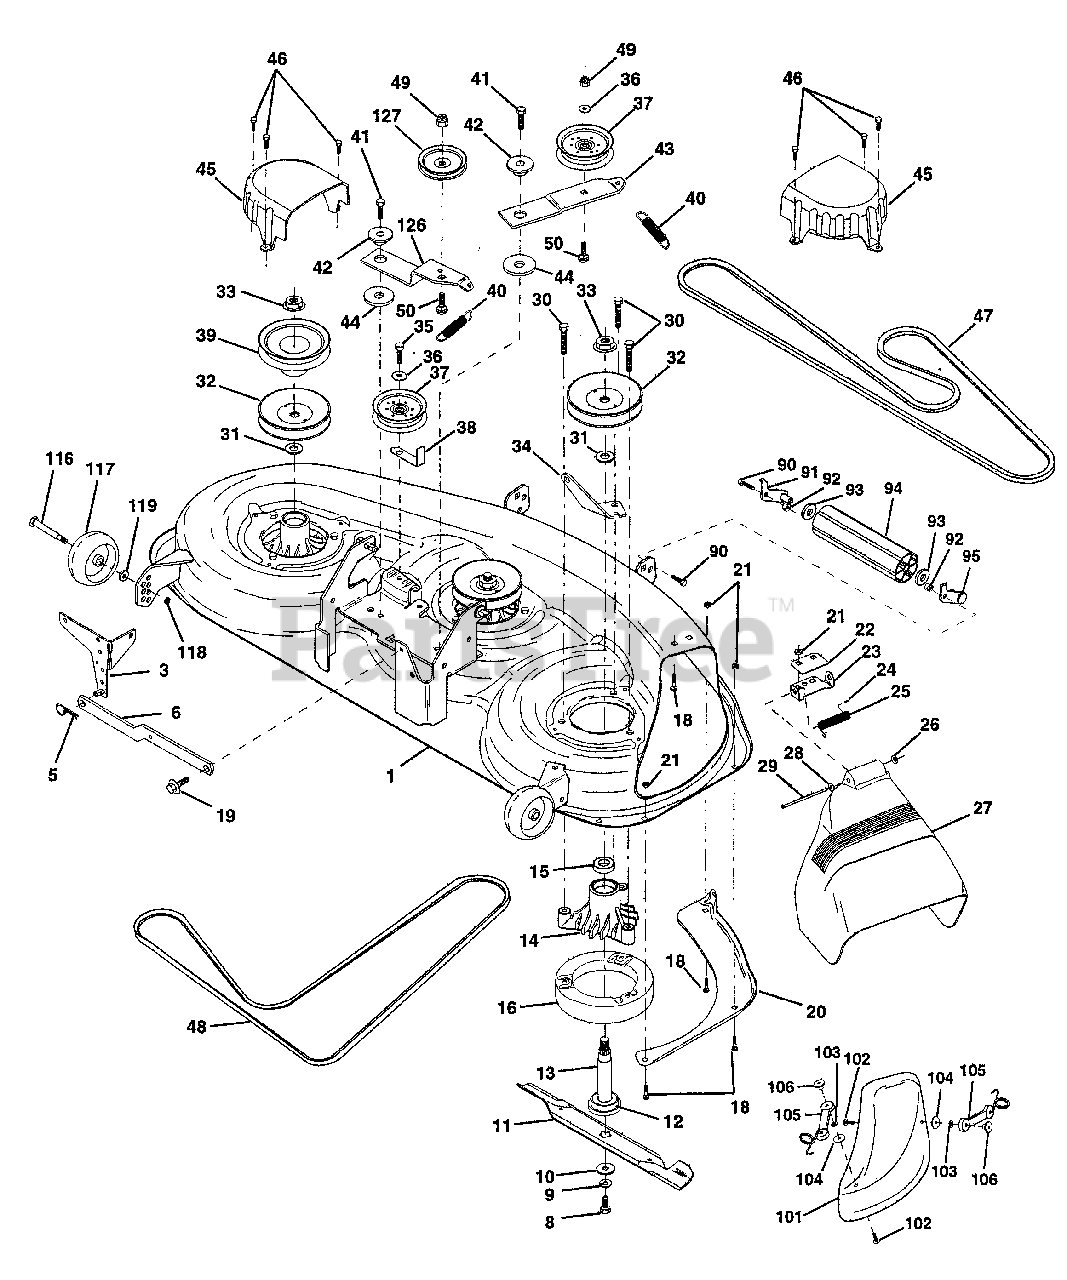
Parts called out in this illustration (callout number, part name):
1	Deck Asm., Mower 46"
3	Bracket Asm., Sway Bar
5	Retainer Spring
6	Arm, Suspension, Rear (Sway Bar)
8	Bolt, Patched 3/8-24 x 1-1/4 Gr. 8
9	Washer, Lock Hvy., Unplated 3/8
10	Washer, Hard Blade, Mower Vented
11	Blade, 46" Mower Deck
12	Bearing, Ball, Mandrel #6204
13	Shaft Asm. w/Lower Bearing
14	Housing, Mandrel
15	Bearing,.-Ball, Mandrel
16	Stripper, Mower Round
18	Bolt, Carriage 5/16-18 x 5/8
19	Bolt, Hex Head, Shoulder 5/16-18
20	Baffle, Vortex Mower 46"
21	Nut, Crownlock 5/16-18 UNC
22	Stiffener, Bracket
23	Bracket, Deflector
24	Cap, Sleeve
25	Spring, Torsion, Deflector
27	Shield, Deflector Mower
28	Washer 11/32 x 5/8 x 16 Ga.
29	Rod, Hinge
30	Screw, Hex Head, Thdroll
31	Washer, Spacer Mower Vented
32	Pulley, Mandrel
33	Nut, Fig. Top Lock Cntr. 9/16
34	Anchor, Spring Deck 46"
35	Screw, Thdroll 3/8-16 x 1-3/4 Tytt
36	Washer 13/32 x 13/16 x 16 Ga.
37	Pulley, Idler, Flat
38	Keeper, Belt, Idler
39	Pulley, Idler, Driven
40	Spring, Secondary 44/46/50 Vent
41	Screw, Thdroll 3/8-16 x 1-1/4 Tytt
42	Spacer, Retainer
43	Arm, Idler Secondary
44	Washer, Hardened
45	Cover, Mandrel Deck
46	Screw, Thdroll. 1/4-20 x 5/8
47	V-Belt, Mower, Secondary
48	V-Belt, Mower, Primary
49	Nut, Crownlock 3/8-16 UNC
50	Bolt, Carriage 3/8-16 x 1-1/2 Gr. 5
90	Bolt, Fin, Hex 3/8-16 UNC x 1
91	Bracket, Asm Noseroller, LH
92	Nut, Lock, Hex w/Ins 3/8-16UNC
93	Washer 17/32 x 7/8 x 16 Ga.
94	Roller, Nose 38 & 42
95	Bracket, asm Noseroller RH
101	Cover, Mulching
102	Screw
103	Washer, Lock #10
105	Latch Asm. Bagger
106	Nut, Weld
116	Bolt, Shoulder
117	Gauge Wheel
118	Nut, Centerlock 3/8-16 UNC
119	Washer 3/8 x 7/8 x 14 Ga.
126	Arm, Idler, Primary Deck 46"
127	Pulley, Idler, V-Groove Dim. 4.25
